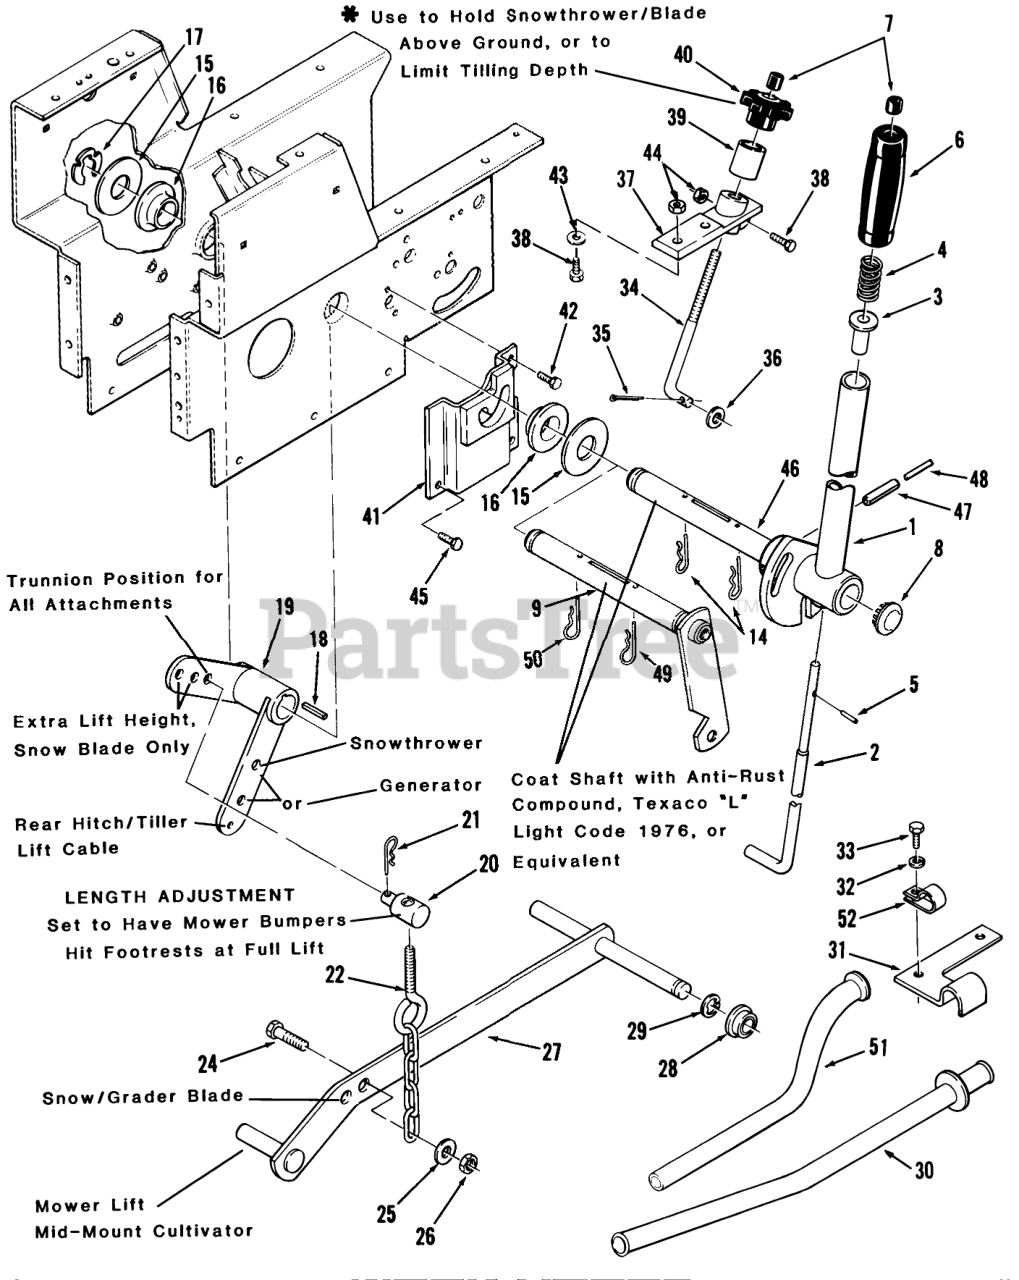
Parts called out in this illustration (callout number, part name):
1	Lift Lever (Includes Items 46, 47, 48)
2	ROD-LATCH LIFT
3	RETAINER-SPRING
4	SPRING-COMPRESSION
5	PIN-SPIROL
6	HANDGRIP
7	CAP-ROD, PLUNGER
8	PLUG
9	Lift lever
14	Pin-Cotter
15	WASHER
16	BEARING-FLANGE
17	Retainer
18	KEY-SQUARE
19	Bellcrank
20	TRUNNION
21	Hairpin
22	CHAIN-LIFT
24	Bolt
25	WASHER 5/16 SAE
26	Nut
27	ASSY LIFT BAR R
28	BUSHING
29	E Ring
30	TUBE ASSY COMPLET R
31	CLAMP-CONDUIT R
32	LOCKWASHER
33	BOLT
33	Bolt
34	Rod
35	Pop Rivet
36	WASHER -4
37	Casting
38	Bolt
39	Sleeve
40	KNOB-LIFT CONTROL
41	Latch Bracket
42	SCREW
43	WASHER 5/16 SAE
44	Nut
45	Bolt
46	SHAFT-LIFT LEVER
47	SPIROL PIN
48	Roll Pin
49	Hairpin
50	Pin-Cotter
51	TUBE-CONDUIT R
52	CLIP
